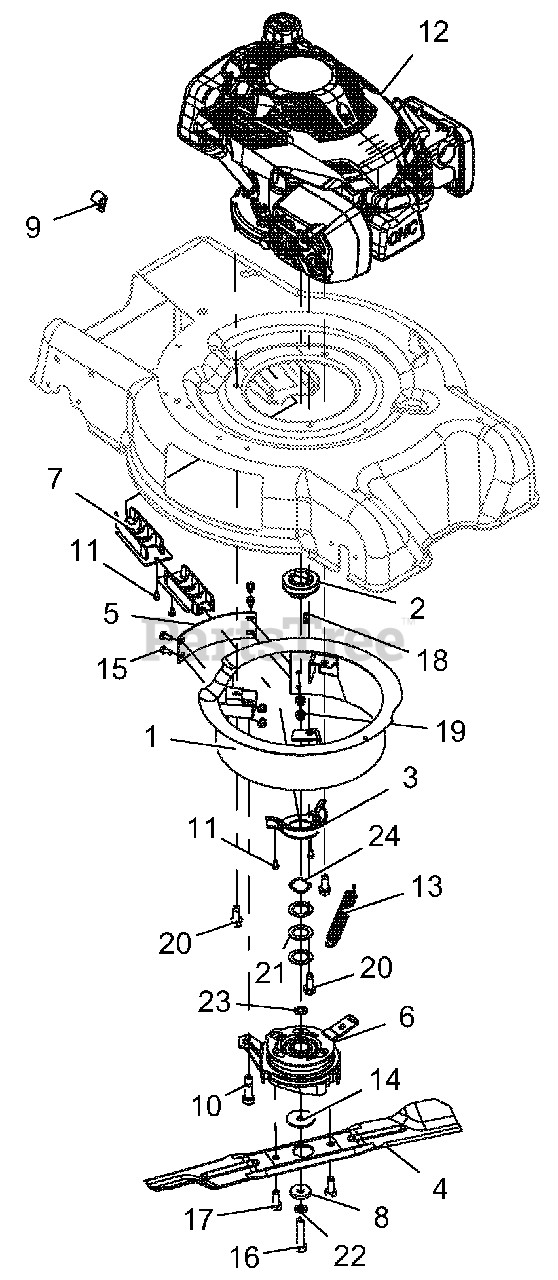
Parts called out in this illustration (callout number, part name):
1	WLDMT, ENCLOSURE - BBC
2	PULLEY, GROUND DRIVE, LM
3	GUIDE, BELT CRANKSHAFT
4	BLADE, MOWER 21" HIGH LIFT-BBC
5	BAFFLE, BBC
6	CLUTCH, RAZOR BBC
7	GUIDE, BELT INNER
8	WASHER-FLAT-STL, .44 X 1.25 X .25 YWZC
9	CLAMP, LM CABLE
10	BLT, SHLDR 12MM X 25 W/M10 THD
11	SCR, TAP 10-24X.375 PRE-COAT 80
12	ENGINE, SUBARU BBC
13	SPRG, EXTENSION BBC
14	WSHR-FL-STL .469X1.75X.10 YWZC
15	BLT-HEX .25-20X.50 GR5 YWZC
16	BLT-HEX .44-20X2.00 GR5 YWZC
17	BLT-HEX M10 X 1.5X20 GR5 YWZC
18	KEY-SQ .188X.188X.625
19	NUT, LK-TOP-FLG .25-20 YWZC
20	SCR-TAP .38-16X1.00 HWH TR YZ
21	WSHR-FL-STL 1.010X1.505X.062 YWZC
22	WSHR-FL-STL .450X.750X.033 YWZC
23	WSHR-FL-STL .459X.750X.105 YWZC
24	WASHER, WAVE
